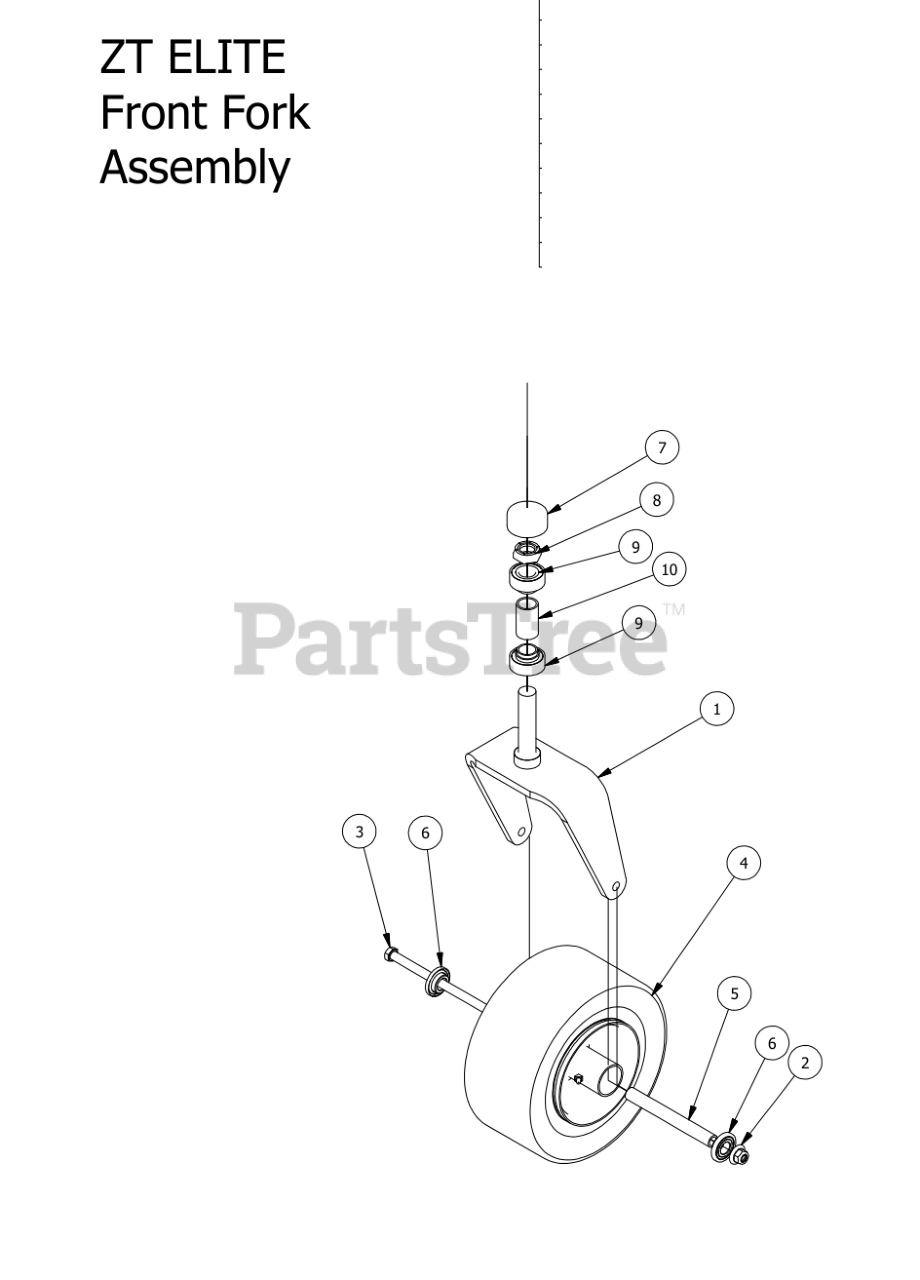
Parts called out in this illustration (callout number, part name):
1	Front Fork
2	1/2-13 Nylon Flange Nut-Orange
3	1/2" x 9" Bolt
4	Tire and wheel assembly
5	Front Wheel Spanner
6	Wheel Bearing
7	Rubber Bearing Cap
8	1" Fine Thread 1/2 Nut
9	Caster Bearing -MZ, 2009 & up
10	ZT/CZT Caster Bearing Spacer
